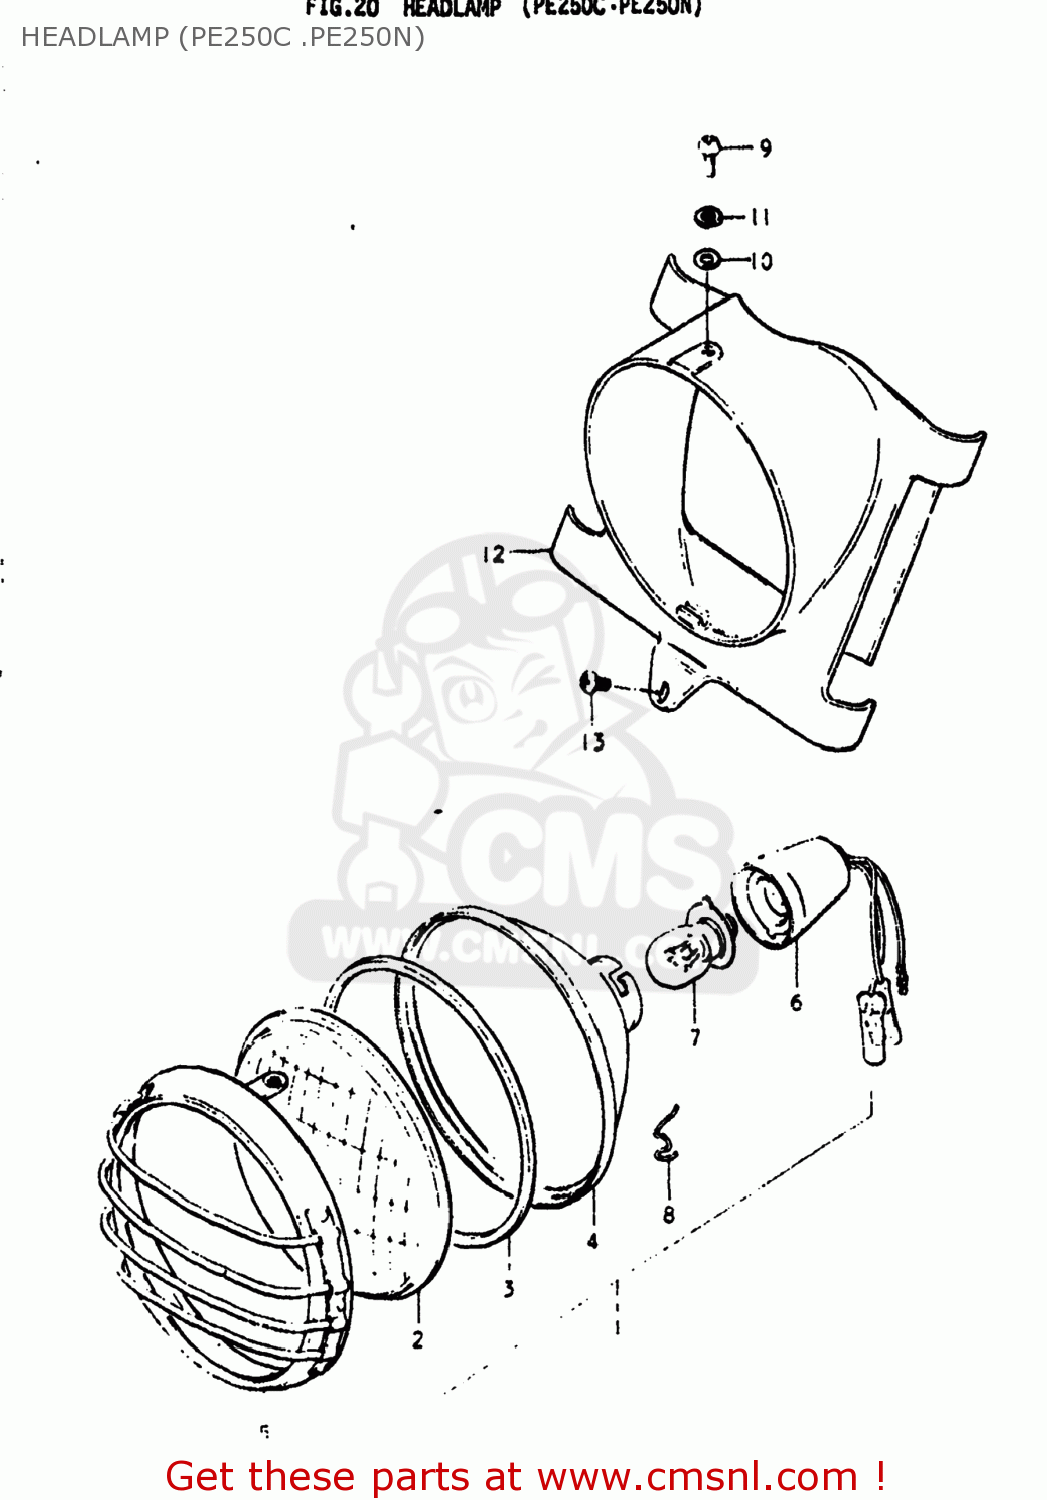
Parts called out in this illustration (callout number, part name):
1	HEADLAMP ASSEMBLY
2	LENS,HEADLAMP
3	GASKET,HEADLAMP LENS (NAS)
4	REFLECTOR,HEADLAMP
5	RIM,HEADLAMP
6	SOCKET,HEADLAMP
7	BULB(6V15/15W/STANLEY,A3598HA)
8	SPRING
9	SCREW
10	WASHER
11	LOCK WASHER
12	HOUSING,HEADLAMP
13	SCREW
